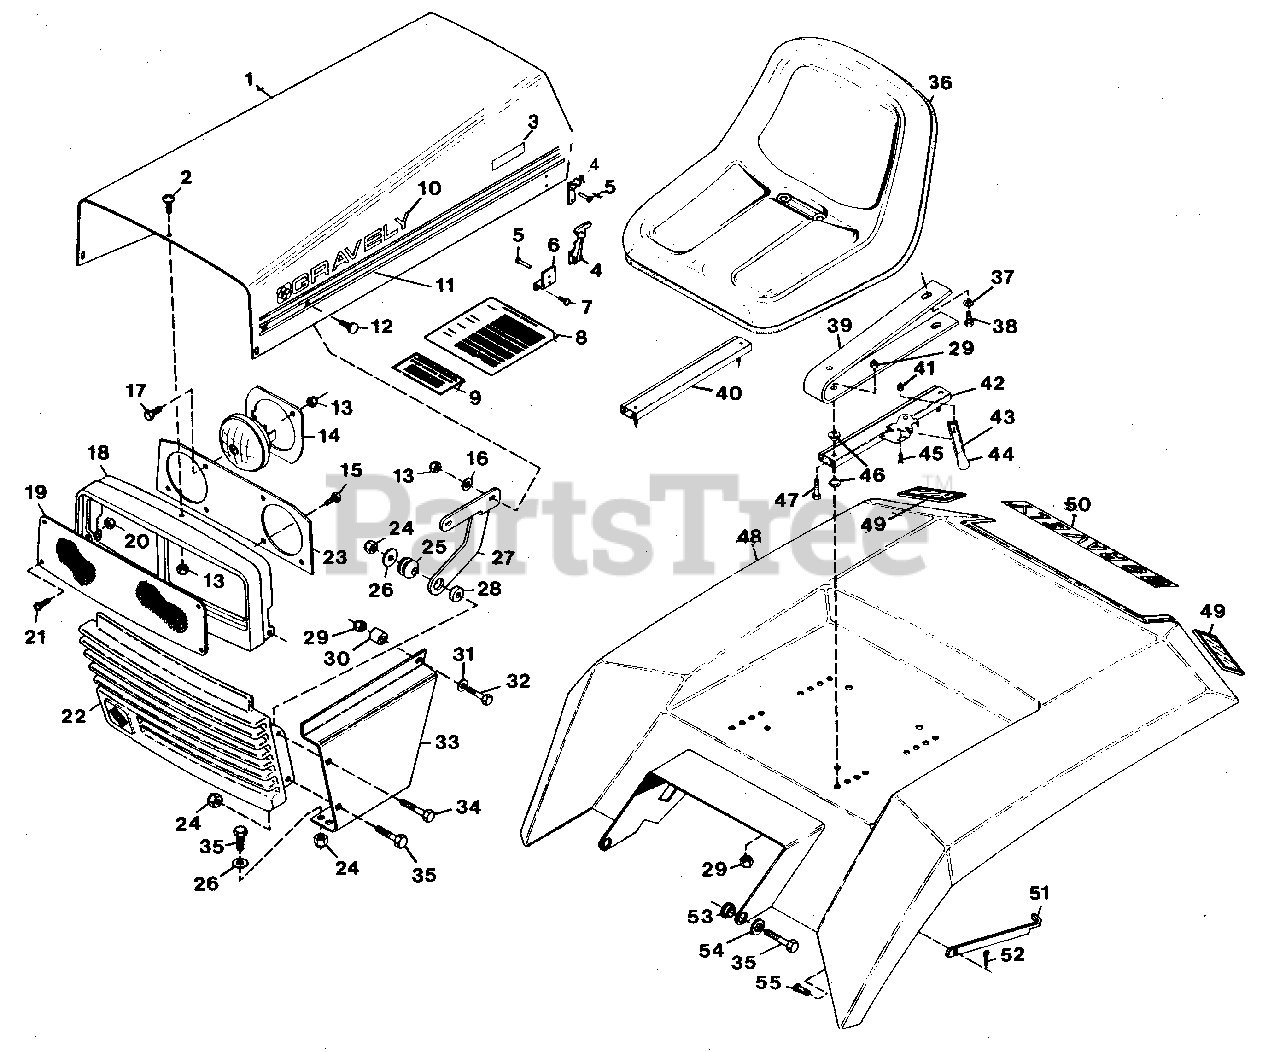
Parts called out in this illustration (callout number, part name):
1	HOOD, SILK SCREEN
2	SCREW, MACHINE 1/4-20 PHD
3	DECAL, MODEL 12-G
3	DECAL, MODEL 16-G
3	DECAL, MODEL 18-G
3	DECAL, MODEL 20-G
4	LATCH, FLEXIBLE
5	RIVET, DOME HEAD
6	BRACKET, HOOD LATCH MOUNTING
7	SCREW, 8-18X.375 PHD CR
8	DECAL, MAINTENANCE
9	DECAL, ELECTRICAL SYSTEM WARNING
10	DECAL, GRAVELY LOGO
11	DECAL, SIDE STRIPE L.H. AND R.H.
12	BOLT, 1/4-20X.75 RD HD SQ NK
13	NUT, LOCK 1/4-20
14	RING, HEADLIGHT RETAINER
15	SCREW, 1/4-20X.50 SELF-TAPPING
16	WASHER, FLAT .281X.625X.065
17	BOLT, HEX 1/4-20X1.00
18	BEZEL, HEADLIGHT
19	PANEL, HEADLIGHT LENSE
20	NUT, LOCK 10-24
21	SCREW, MACHINE 10-24X.75 PHD
22	CASTING, GRILLE
23	PANEL, HEADLIGHT REFLECTOR
24	NUT, LOCK 3/8-16
25	GROMMET
26	WASHER, FLAT .438X1.000X.083
27	HINGE, HOOD L.H.
27	HINGE, HOOD R.H.
28	SPACER
29	NUT, LOCK 5/16-18
30	SPACER, .375X.100X1.00
31	WASHER, FLAT .344X.688X.065
32	BOLT, HEX 5/16-18X1.75
33	PANEL, SIDE L.H.
33	PANEL, SIDE R.H.
34	BOLT, HEX 3/8-16X2.00
35	BOLT, HEX 3/8-16X1.00
36	SEAT, HIGH BACK
37	WASHER, LOCK 5/16 REG.
38	BOLT, HEX 5/16-18X.75
39	SPRING, SEAT
40	ADJUSTER, SEAT
41	NUT, LOCK 10-24
42	ADJUSTER, SEAT W/LATCH
43	HANDLE, SEAT SLIDE
44	TIP, LEVER
45	SCREW, MACHINE 10-24X.625 PHD
46	SPACER
47	BOLT, HEX 5/16-18X1.25
48	WELDMENT, SEAT PAN
48	WELDMENT, SEAT PAN NOTCHED
49	REFLECTOR, RED SAFETY
50	DECAL, GRAVELY LOGO
51	STRAP, FENDER HOLD-UP
52	PIN, COTTER .06X.75
53	BUSHING, REAR FENDER
54	WASHER, FLAT .406X.812X.065
55	PIN, CLEVIS .250X.406
